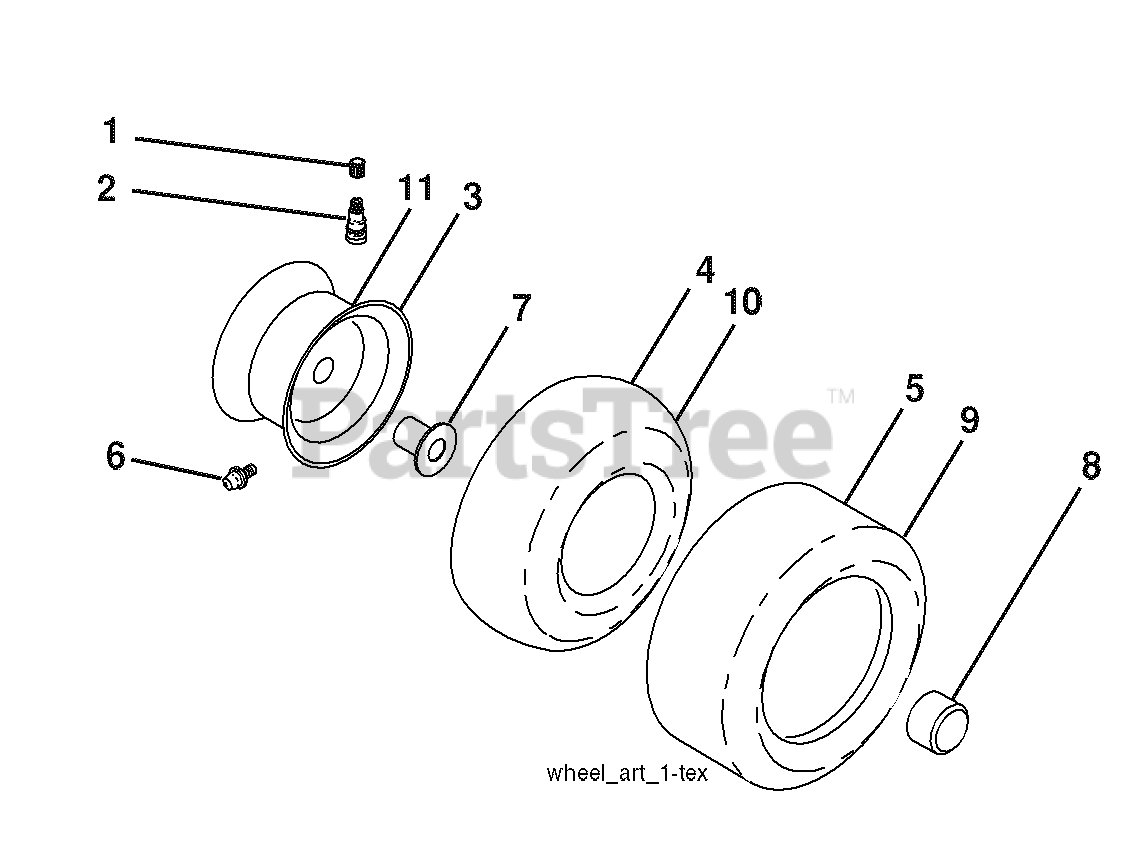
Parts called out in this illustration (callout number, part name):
1	Cap Valve Tire
2	Stem Valve
3	Rim Front Service
4	Tube Front
5	Tire Front 15 x 6.0-6 Service
6	Fitting Grease
7	Bearing Flange
8	Cap Axle Blk 1 50 x 1 00
9	Tire R T 20 x 10-8 Service
10	Tube Rear
11	Rim Asm 8" Rear Service
11	Sealant, Tire
